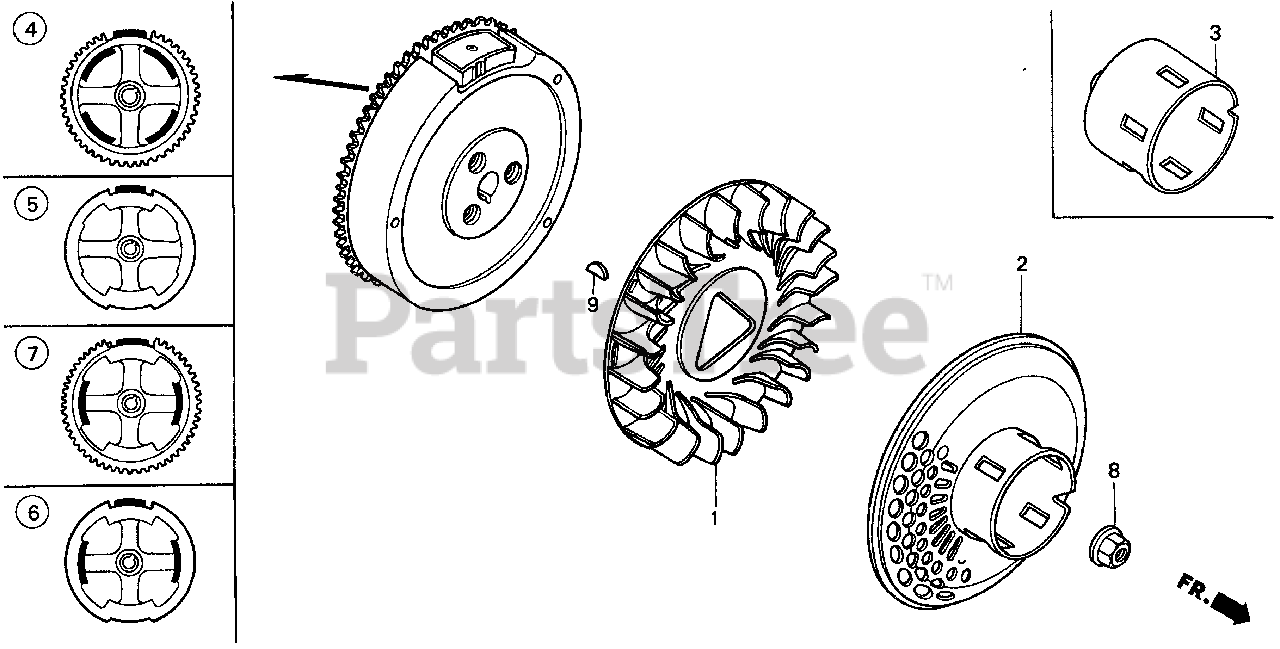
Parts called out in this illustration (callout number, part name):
1	FAN, COOLING
2	PULLEY, STARTER (SCREEN GRID)
5	FLYWHEEL
8	NUT, SPECIAL (16MM) (1)
9	KEY, SPECIAL WOODRUFF (25X18)
